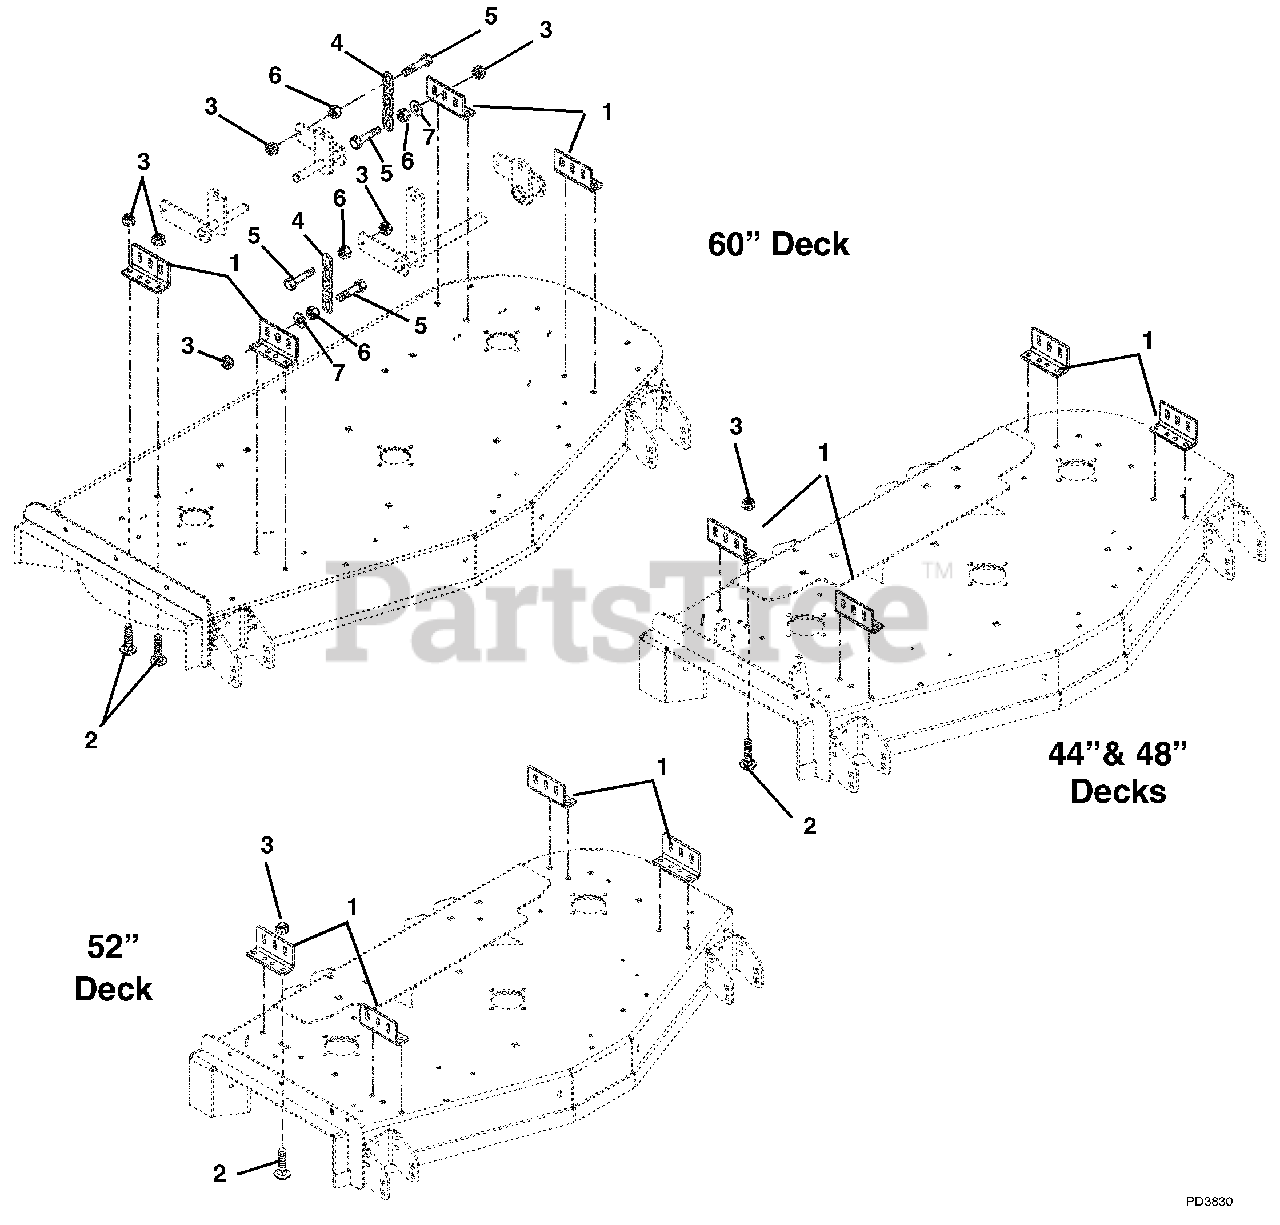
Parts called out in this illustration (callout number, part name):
1	Bracket, Mower Mounting
2	Bolt-Round Head Square Neck .38-16 x 1.00 Grade 2
3	Nut-Locking-Top-Flange .38-16
4	Chain, Link
5	Bolt-Hex .38-16 x 1.50 Grade 5
6	Nut-Hex .38-16
7	Washer-Flat-Steel .406 x .812 x .065
